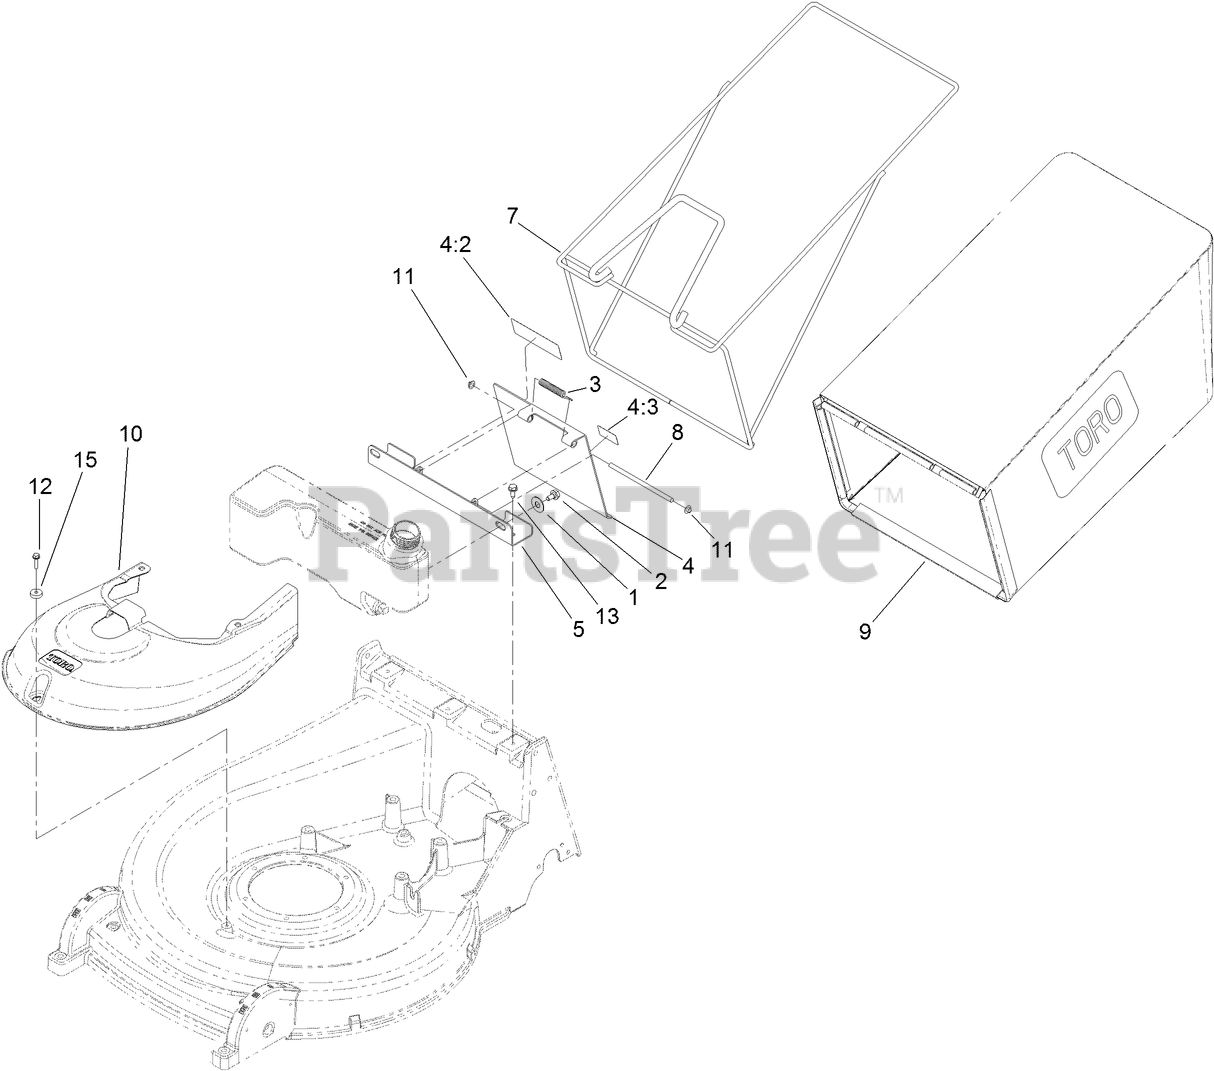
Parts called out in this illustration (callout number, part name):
1	WASHER-PLASTIC
2	BOLT-SHOULDER
3	SPRING-TORSION
4	DOOR ASM
4:2	DECAL-DANGER
4:3	Decal-Grease
5	BRACKET-MOUNT, BAG/DOOR
7	FRAME-BAG
8	ROD-PIVOT, DOOR
9	GRASS BAG ASM
10	COVER-SPINDLE
11	NUT-PUSH
12	SCREW-HWHTF
13	SCREW-HWHTF
15	WASHER
